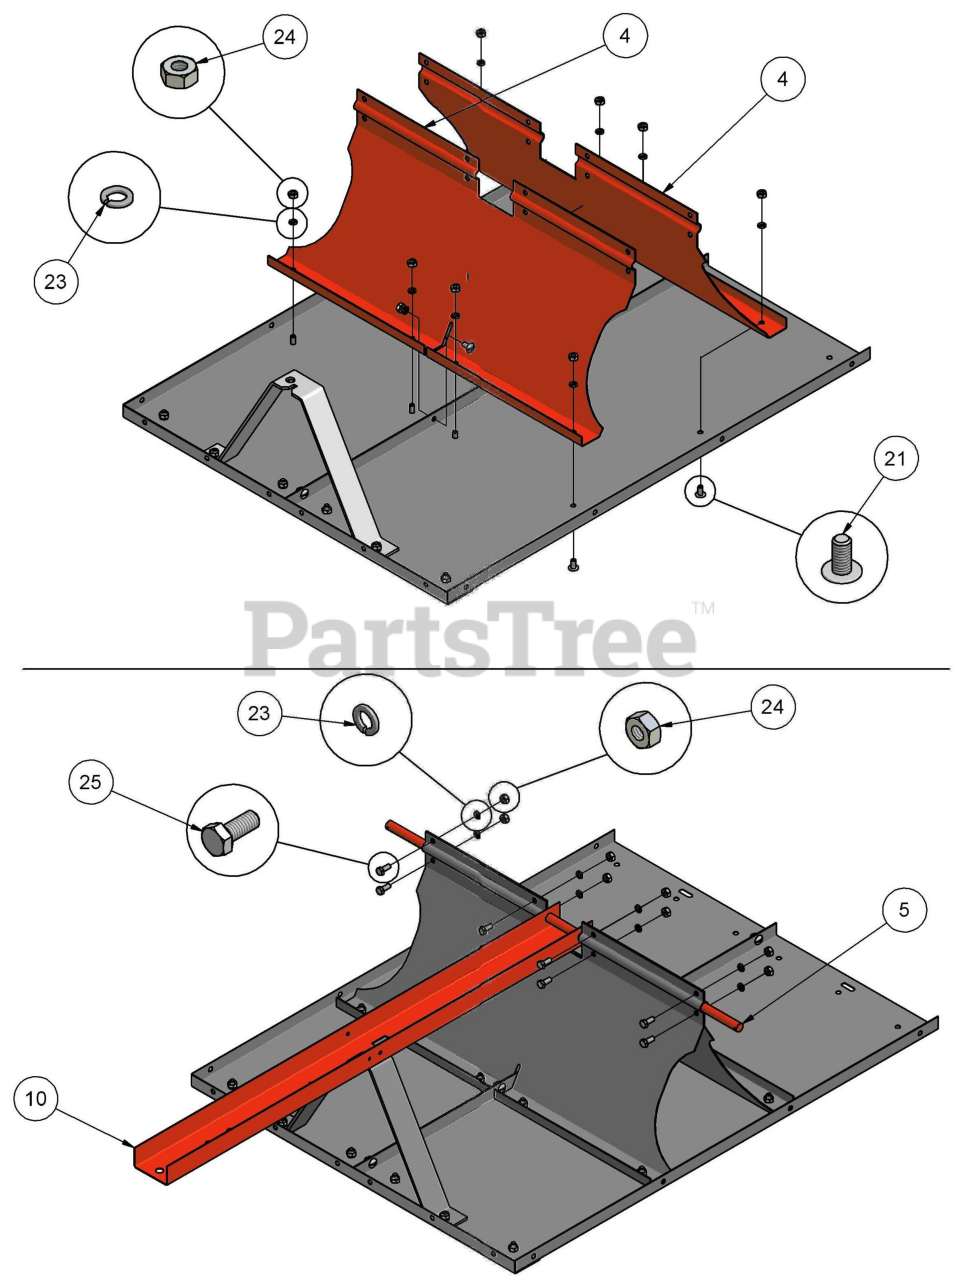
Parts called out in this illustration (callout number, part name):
4	WHEEL AXLE SUPPORT
5	WHEEL AXLE
10	HITCH TONGUE
21	M8 X 16 TRUSS HEAD BOLT
23	8MM LOCK WASHER
24	8MM HEX NUT
25	M8 X 20 HEX BOLT
